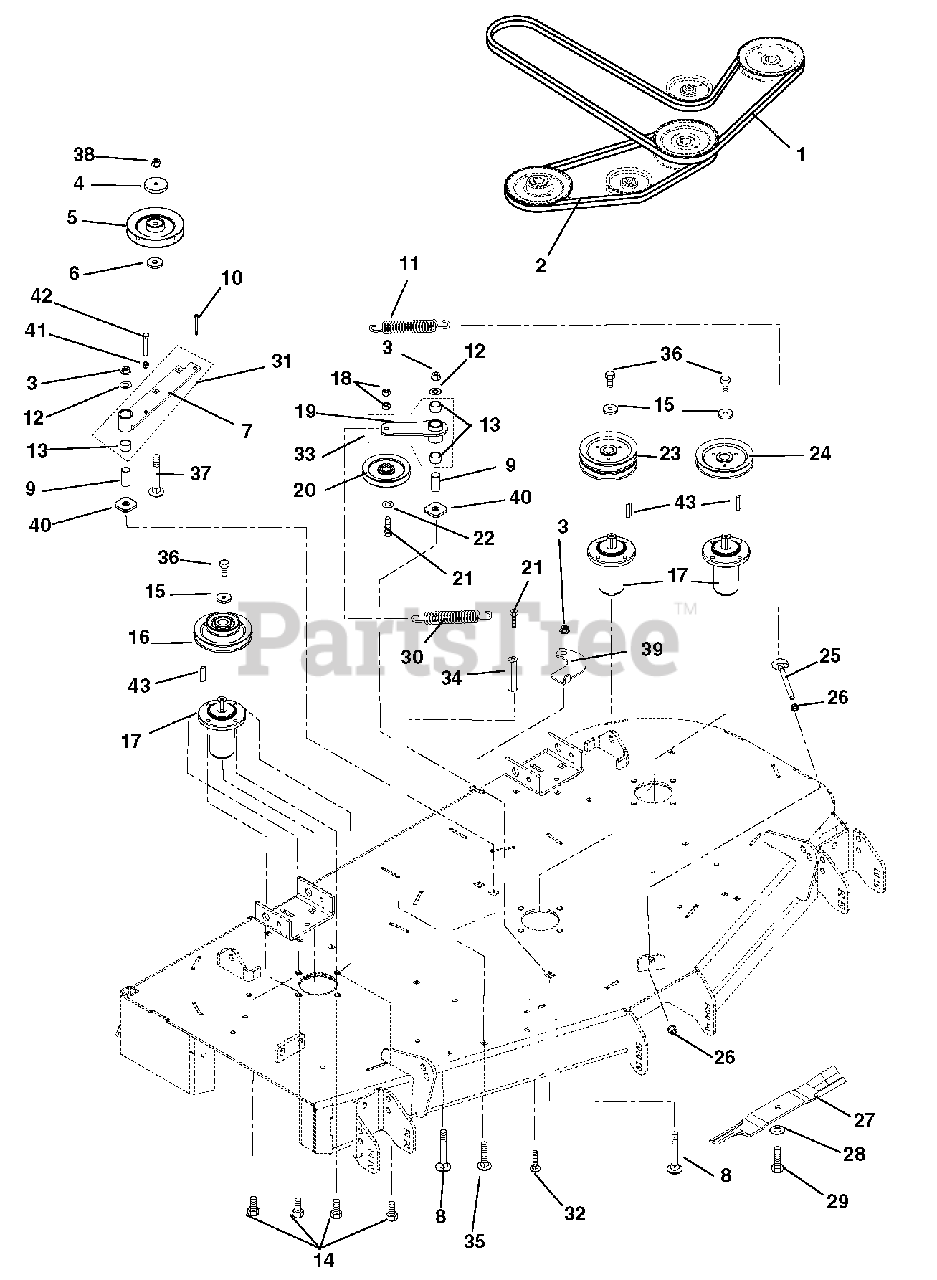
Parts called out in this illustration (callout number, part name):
1	Belt, BB-Wrapped Clutching Hex
2	V-Belt, 63" Long Cog B-Section
3	Nut, .50-13 Nyloc Flange
4	Cap, Idler Bearing Sealing
5	Sheave .50" ID x 6.00" OD V-Idler SNGL Bearing
6	Bushing, Spacer .502 x .997 x 0.50
7	Arm, Idler
8	Bolt, Round Head Square Neck .50-13 x 3.50 Grade 5
9	Bushing, Spacer .502 x .997 x 2.03
10	Bolt, Shoulder .38-16 x .30 Hex
11	Spring, Extension
12	Washer, Flat Steel .563 x 1.38 x .109
13	Bushing, 1.00 x 1.125 x 1.936
14	Bolt, Hex .38-16 x 1.00 (Torque = 380-480 lbf-in (42.93-54.23 N•m))
15	Retainer Sheave
16	Pulley, Double 1" ID x 6.75" & 4.25" OD
17	Assembly, Spindle – Long G3500
18	Nut, Locking-Center .38-16
19	Weldment, Idler Arm
20	Sheave, .38" ID x 5.00" OD V-Idler
21	Bolt, Hex .38-16 x 2.25
22	Washer, Flat Steel .406 x .812 x .065
23	Pulley, Double-1" ID x 6.75" OD
24	Pulley, V 1" ID x 6.75" OD
25	Bolt, .38-16 x 4.50 .62 Diameter Eye
26	Nut, Hex, Jam .375-16
27	Blade, Mower (20.50")
28	Washer, Bellville .63 x 1.625 x .14
29	Bolt, Hex .62-18 x 1.75 Grade 8 (Torque = 115-160 lbf-in (12.99-18.08 N•m))
30	Spring, Extension
31	Assembly, PTO Idler Pivot Arm (Includes item # 7 and item # 13)
32	Bolt, Round Head Square Neck .50-13 x 1.5, Full Thread, Grade 5
33	Assembly, Idler Pivot Arm (Includes item # 13 and item # 19)
34	Nut, Coupling .375-16 x 1.75
35	Bolt, Round Head Square Neck .38-16 x 1.00
36	Bolt, Round Head Square Neck .38-16 x 2.75 Grade 8
37	Bolt, Round Head Square Neck .50-13 x 3.00 Grade 8
38	Nut, Locking-Center .50-13
39	Stop, PM320 PTO Idler Arm
40	Washer, Flat Steel .640 x 1.75 x .250
41	Nut, Hex .38-16
42	Bolt, Hex .38-16 x 2.75
43	Key, Square .25 x .25 x 1.00 RC 40-50
